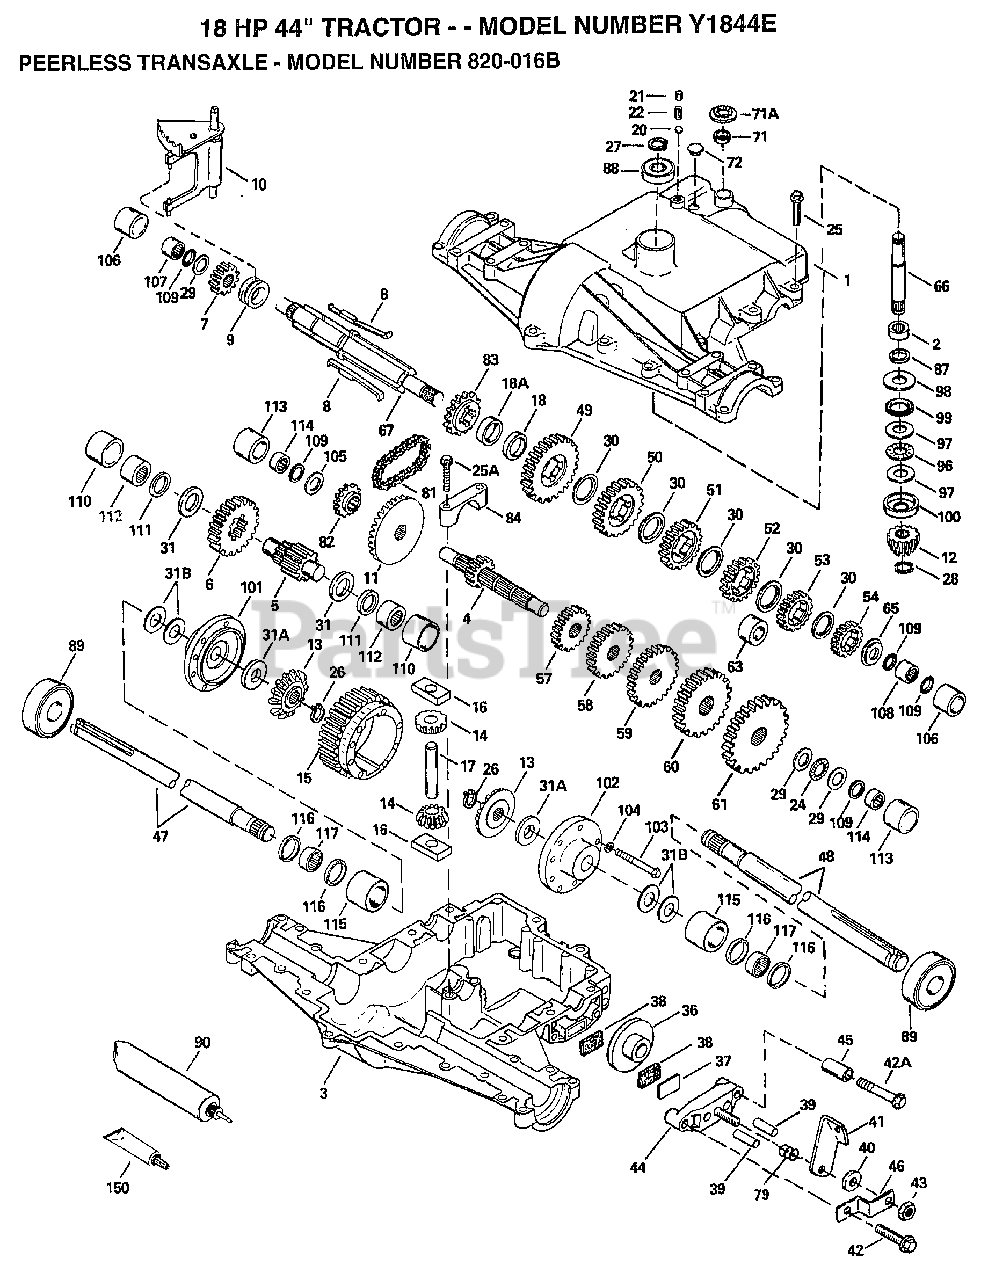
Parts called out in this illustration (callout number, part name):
1	COVER TRANSAXLE
3	BEARING NEEDLE
3	CASE TRANSAXLE
4	SHAFT COUNTER
5	SHAFT, OUTPUT, 9T
6	GEAR, OUTPUT, 35T
7	GEAR, SPUR, 15T
9	COLLAR SHIFT
10	ROD AND FORK ASSY SHIFT
11	GEAR BEVEL, 33T
12	BEVEL PINION, 13T
14	PINION, 10T
15	GEAR, RING, 31T
16	BLOCK DRIVE
18	SPACER, .350/.340 THICK
18A	SPACER, .276/.268 THICK
20	BALL STEEL, 5/16" DIA.
21	SCREW, 3/8-16 X 3/8"
24	THRUST BEARING
25	SCREW HEX HD 5/16-18 X 1-1/4
25A	SCREW, 1/4-20 X 1-1/4
28	RETAINING RING
29	WASHER THRUST
30	WASHER THRUST
31	WASHER THRUST
31B	WASHER THRUST
37	PLATE BRAKE PAD
41	LEVER BRAKE
42	SCREW, 1/4-20 X 1-1/4
42A	SCREW, 1/4-20 X 2-1/4
43	LOCKNUT 5/16-24
44	HOLDER BRAKE PAD
46	BRKT BRAKE LEVER
47	AXLE, 12-5/16" LONG
48	AXLE, 16-3/16" LONG
49	GEAR, SPUR, 41T
50	GEAR, SPUR, 35T
51	GEAR, SPUR, 30T
52	GEAR, SPUR, 25T
53	GEAR, SPUR, 22T
54	GEAR, SPUR, 19T
54	GEAR, SPUR, 15T
58	GEAR, SPUR, 20T
59	GEAR, SPUR, 25T
60	GEAR, SPUR, 28T
61	GEAR, SPUR, 31T
66	SHAFT INPUT
67	SHAFT BRAKE
71	SEAL SQUARE CUT
72	PLUG, THRDED, 9/16-18
81	CHAIN, ROLLER
82	SPROCKET 9T
83	SPROCKET 18T (REV)
84	BEARING CAP
87	OIL SEAL 3/4
88	BEARING BALL
89	BEARING BALL
90	GREASE BENTONITE, 32 OZ.
96	BEARING THRUST
97	WASHER THRUST
100	WASHER CUPPED
101	CARRIER DIFF THREADED HOLES
102	CARRIER DIFF
103	SCREW, 1/4-20 X 2-1/4
104	WASHER LOCK 1/4
107	BEARING NEEDLE
108	BEARING NEEDLE
110	SLEEVE STEPPED
111	RING SQ CUT
112	BEARING NEEDLE CAPPED
113	SLEEVE STEPPED
114	BEARING NEEDLE CAPPED
115	SLEEVE STEPPED
116	RING SQ CUT
117	BEARING NEEDLE
150	GASKET ELIMINATOR
